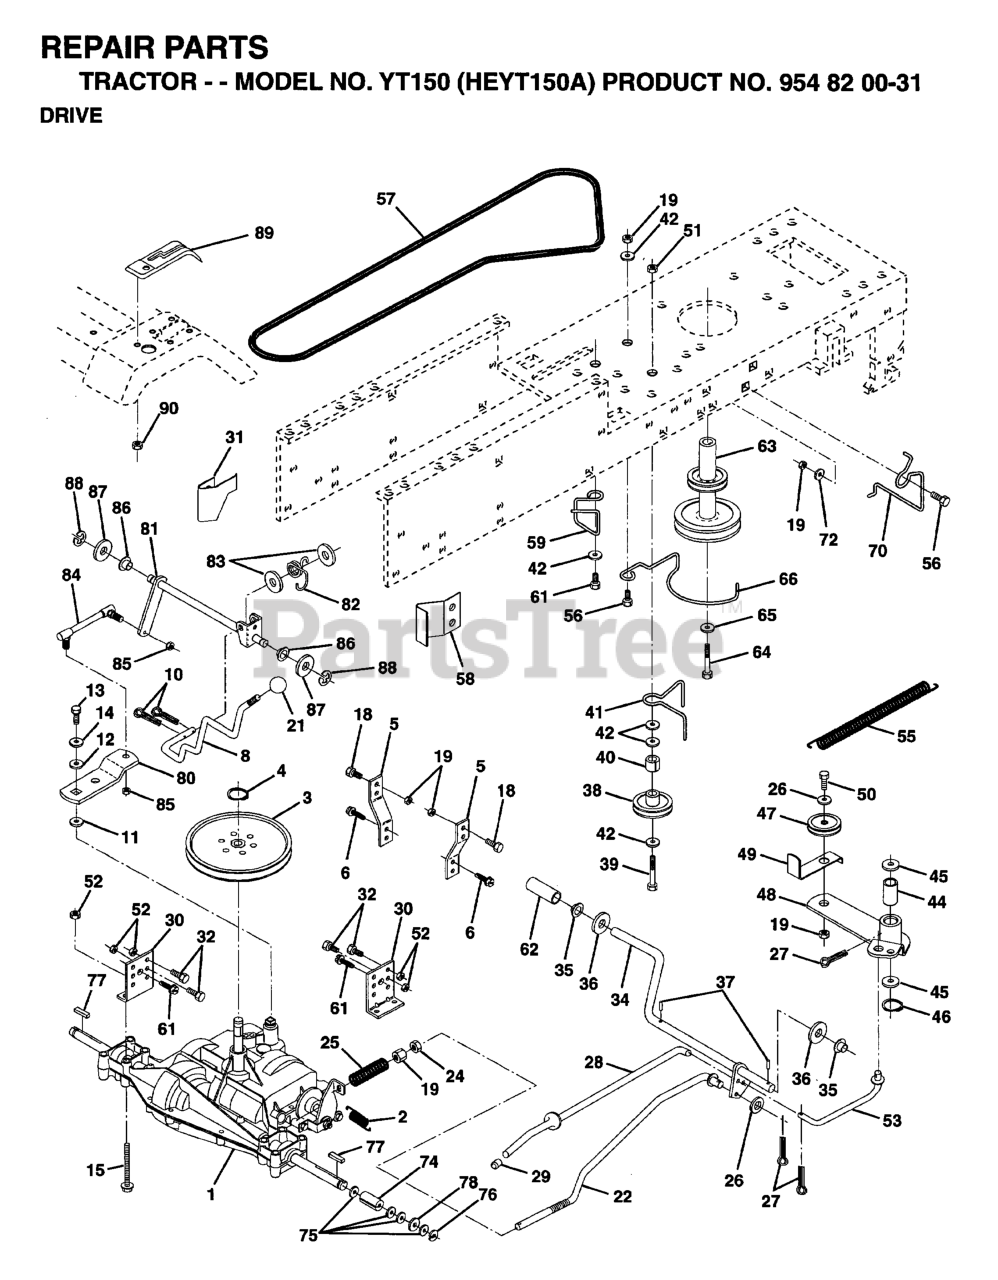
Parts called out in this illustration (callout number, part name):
1	TRANSAXLE ASSY 6 SPD
2	SPRING,BRAKE RETURN
3	PULLEY TRANS
4	RETAINING RING LT
5	STRAP TORQUE
6	SCREW.THDROL.5/16-18X3/4.TTY
10	PIN COTTER
11	WASH-SHFT PLT LT
12	Washer 15/32 x 3/4 x 16 Gauge
13	BOLT 1/4-28X3/4
14	LOCKWASHER
15	BOLT HEX 5/16-18 GR 5
19	NUT
21	KNOB.DUCKHEAD.1/2
24	NUT
25	SPRING ROD LT
26	WASHER
27	COTTER PIN
28	ROD BRAKE PARK LT
29	PLUNGER CAP
30	BRACKET TRANSAXLE
31	KEEPER BELT LH
32	BOLT
34	SHAFT PEDAL FOOT
35	BEARING.NYLON
37	DRIVE PIN
38	PULLEY.IDLER.FLAT
41	BELT KEEPER LT NLA
42	WASHER
44	BEARING LT (2 2)
47	IDLER PULLEY
49	RETAIN BELT
50	BOLT
52	LOCKNUT
53	LINK, CLUTCH LT
55	SPRING, RETURN LT
57	V-BELT
59	KEEPER CENTER SPAN
61	SCREW
62	COVER, PEDAL (1 2)
63	PULLEY.ENG.CL.MECH.SLVR.LT/YT
64	BOLT
65	LOCKWASHER
66	KEEPER, BELT
70	KEEPER BELT ENG
72	WASHER
77	SQUARE KEY
81	SHAFT ASMBLY
82	SPRING,TORSION
83	WASHER
85	NUT LOCK CENTER 1/4 -28 FNTHD
86	BUSHING.STEERING.ROD LTB-WSL
90	NUT.PUSH.3/16
